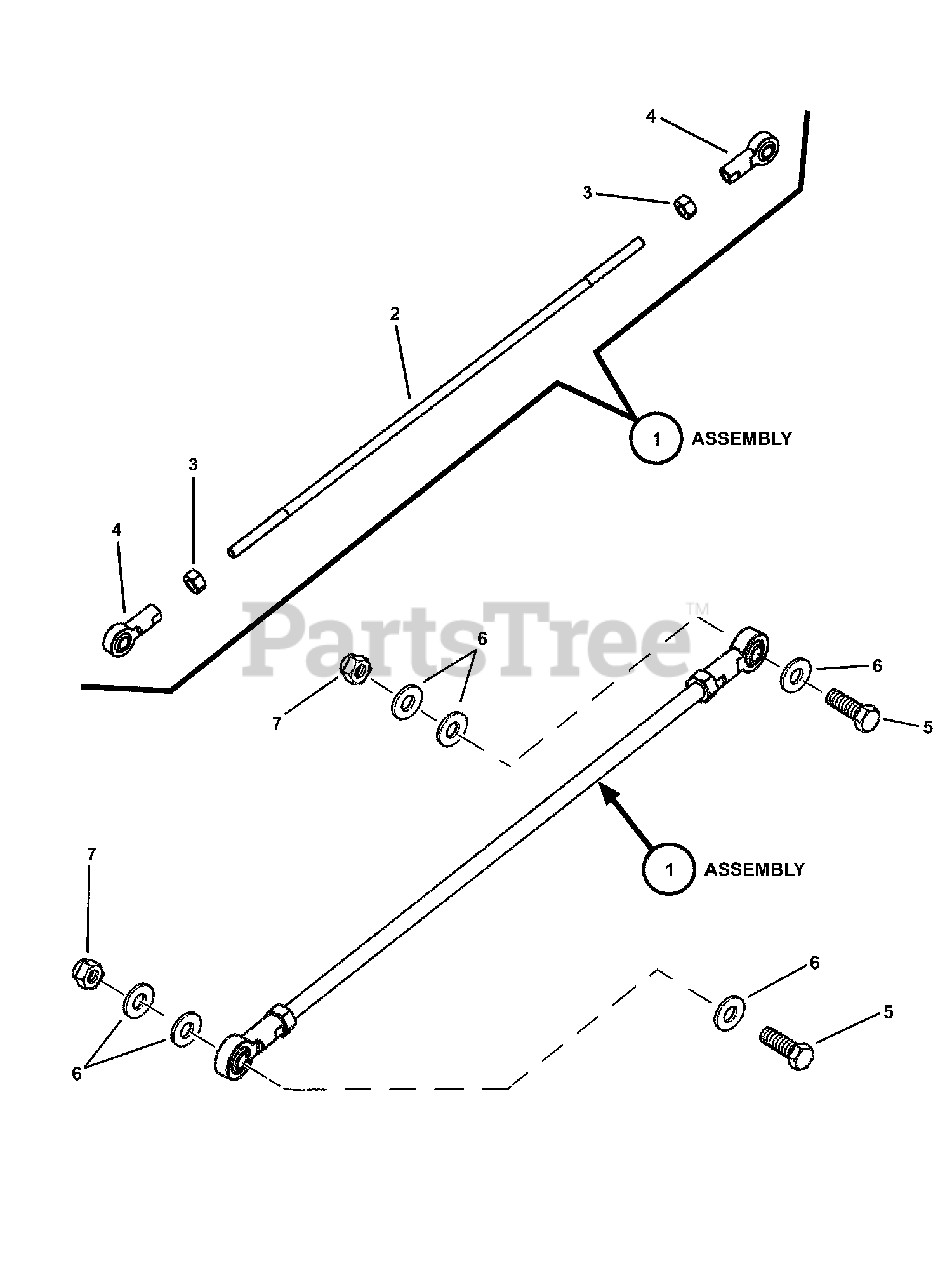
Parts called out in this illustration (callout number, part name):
1	ASSY, Pump Control Linkage (Incl. 3 items below)
2	LINKAGE ROD, Pump Control (5/16-24 threads, both ends)
3	NUT, 5/16-24 Hex GR 5 (2 per assembly)
4	BALL JOINT 5/16-24 (2 per assembly)
5	BOLT, 5/16-18 X 1-1/4 GD5 YZ
6	WASHER, 5/16" Flat
7	NUT, 5/16-18 HEX NYLON LOCK
